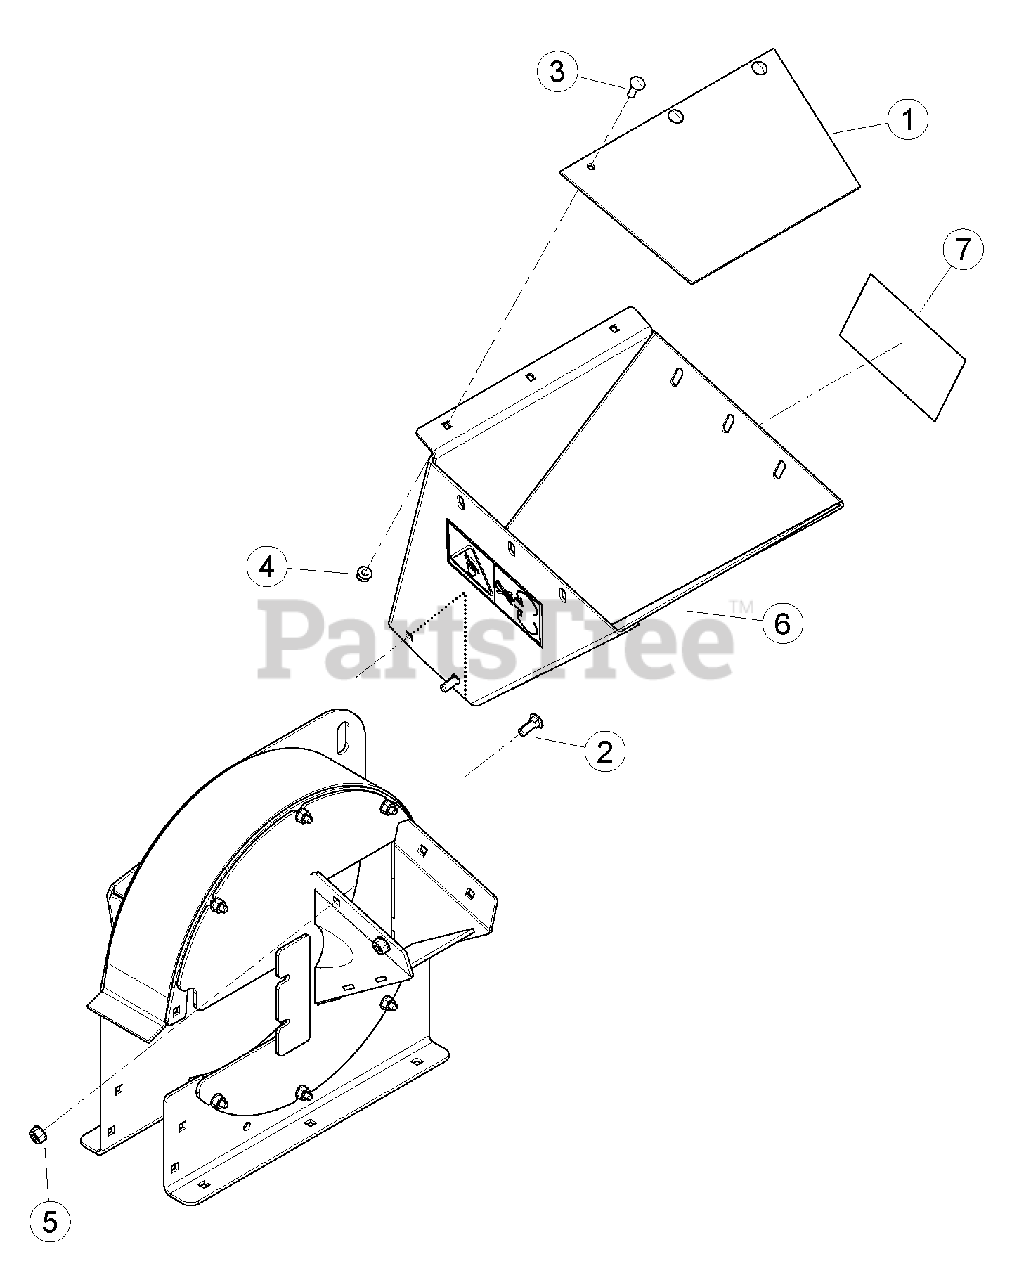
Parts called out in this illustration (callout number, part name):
1	FLAP, CHIPPER CHUTE
2	BOLT, 3/8 X 1" CRG GR5 NC ZP
3	BOLT, 5/16 X 1" GR5 CRG ZP
4	NUT, 5/16-18 NYLOCK-FLANGE
5	NUT, 3/8-16 NYLOCK FLANGE
6	ASSEMBLY, HOPPER
7	DECAL, BLADE DANGER ISO
